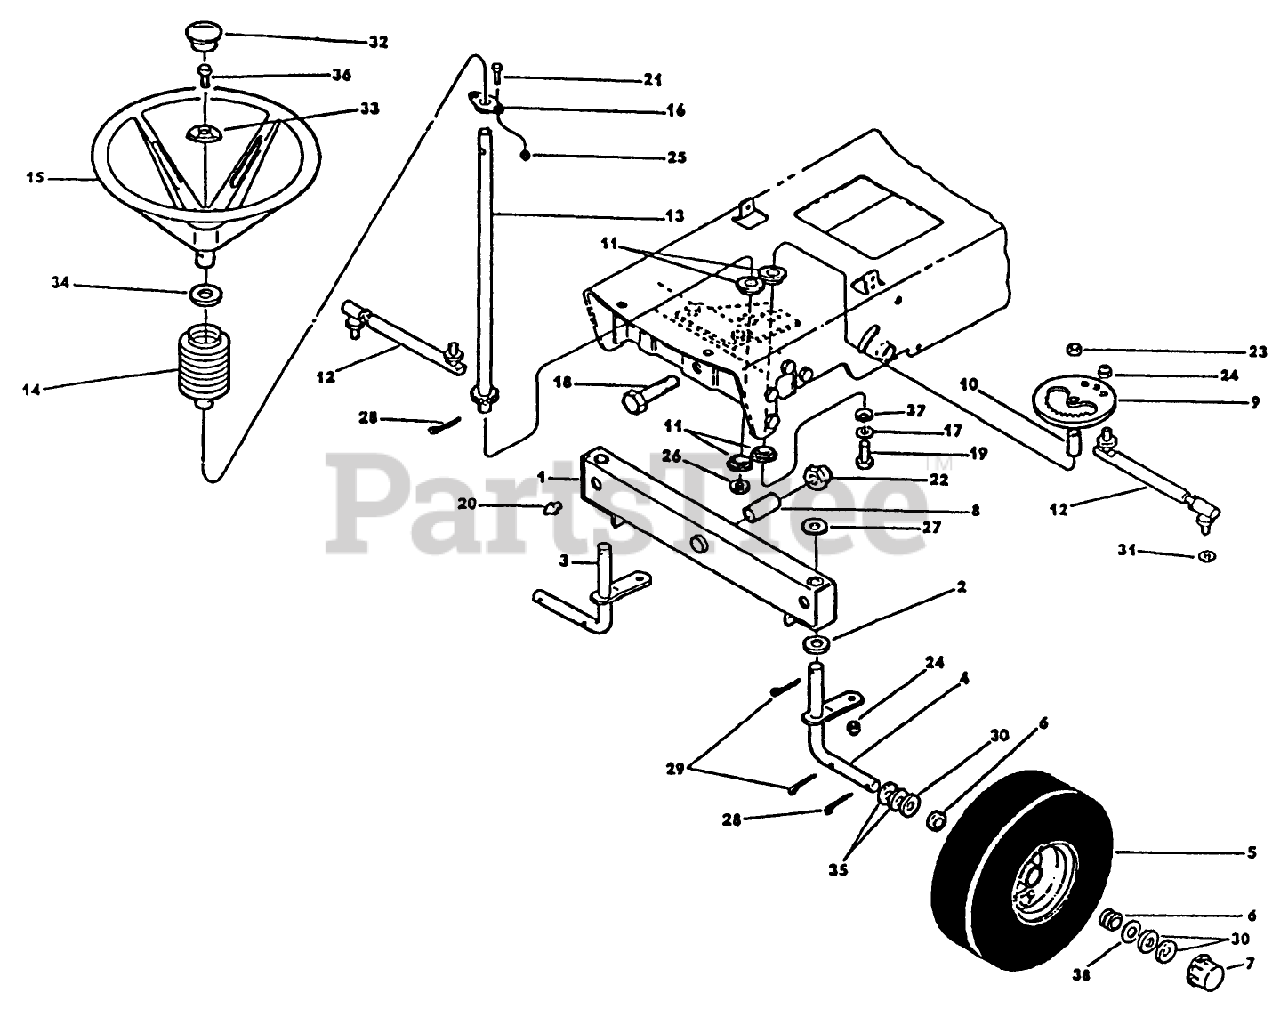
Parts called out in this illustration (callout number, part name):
3	RH FRT SPDL WA (BLUE)
8	SPACER
10	SPACER
11	BEARING - FLANGE
12	BALL JOINT
13	STEERING SHAFT WA
16	BEARING AY.
17	WASHER
21	SCREW-HH
22	NUT-HEX CONE LOK
23	NUT-HEX
24	HEX NUT
25	NUT-LOCK, CONE
26	SPACER
30	WASHER
36	SCREW - HEX
